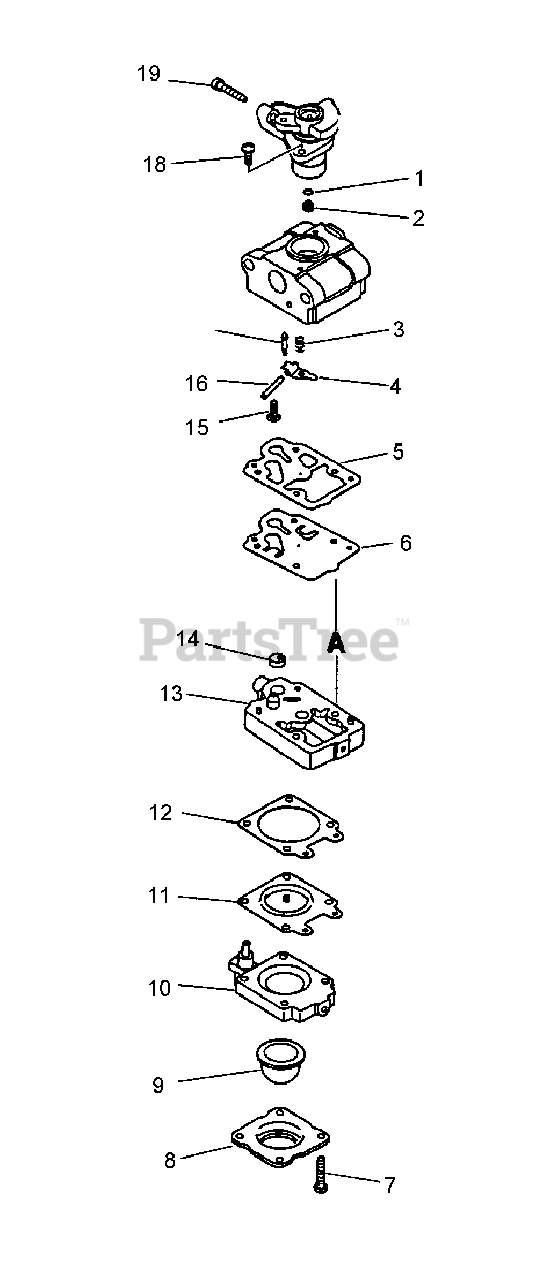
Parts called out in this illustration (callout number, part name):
1	O-RING
2	JET
3	SPRING, METERING LEVER
4	LEVER, METERING
5	GASKET, PUMP
6	DIAPHRAGM, PUMP
7	SCREW, PUMP COVER
8	RETAINER, PURGE BULB
9	BULB, PURGE
10	PURGE BASE ASSY
11	DIAPHRAGM, METERING
12	GASKET, METERING
13	BASE, PURGE
14	STRAINER
15	SCREW, METERING LEVER PIN
16	PIN, METERING LEVER
17	VALVE, INLET NEEDLE
19	SCREW, IDLE ADJUST
